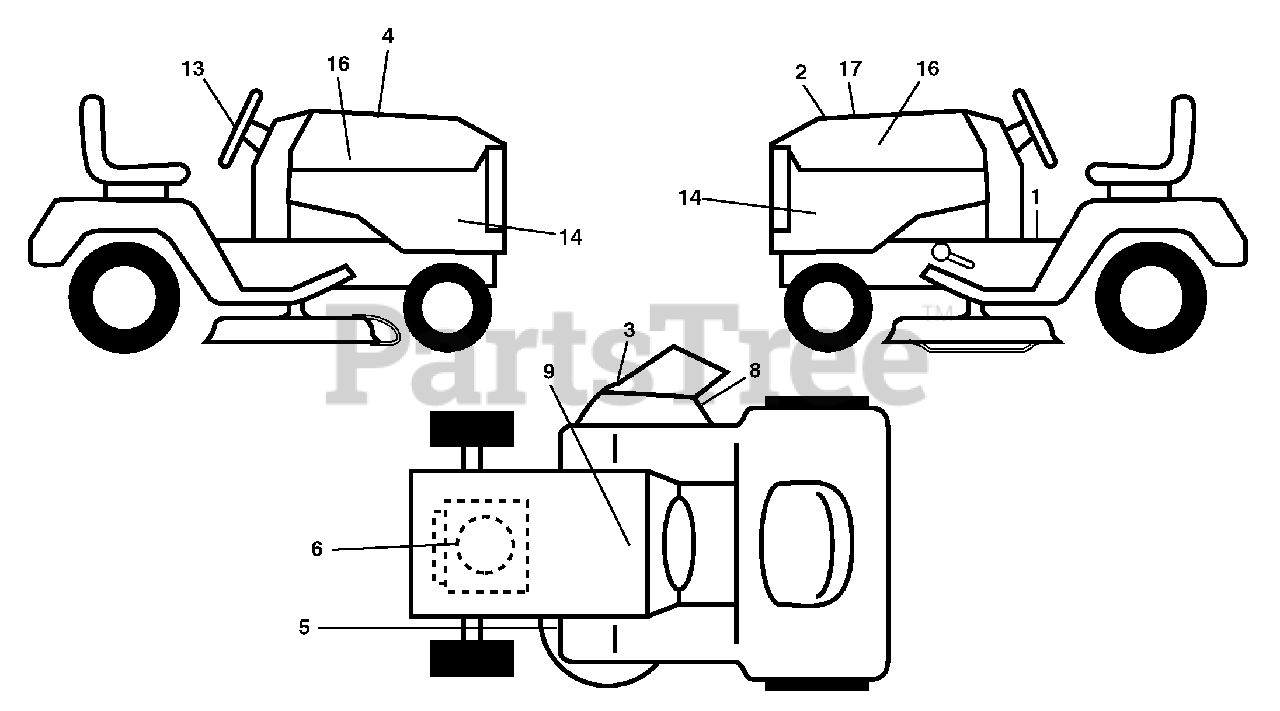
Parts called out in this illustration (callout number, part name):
1	Decal, Operator's
2	Decal, Hood Insert
3	Decal, Warning
4	Decal, Hood Cust Resp
5	Decal, Caution
6	Decal, Eng. HP
8	Decal, Mower Sch.
9	Decal, Battery Dnge/Poi
13	Decal, Steering Whl
14	Decal, Panel Side
16	Decal, Hood Logo
17	Decal, Replacement
